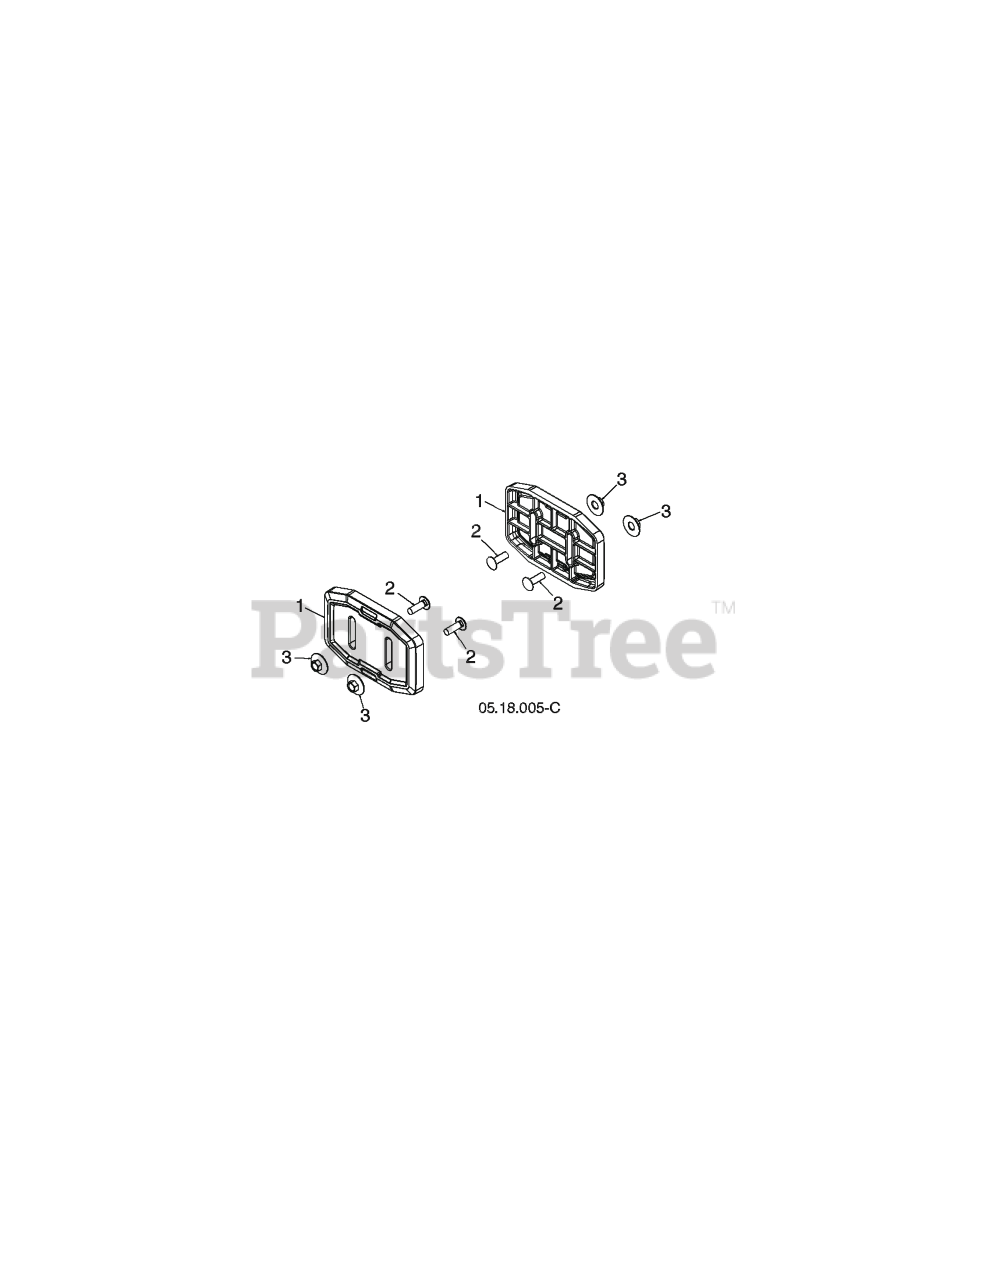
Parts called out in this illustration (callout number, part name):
1	PLATE.SKID.SHOE.COMPOSITE
2	BOLT.CARR.5/16-18X1.BLACK
3	NUT.HEX.FL 5/16-18 TOP LCK BLK
